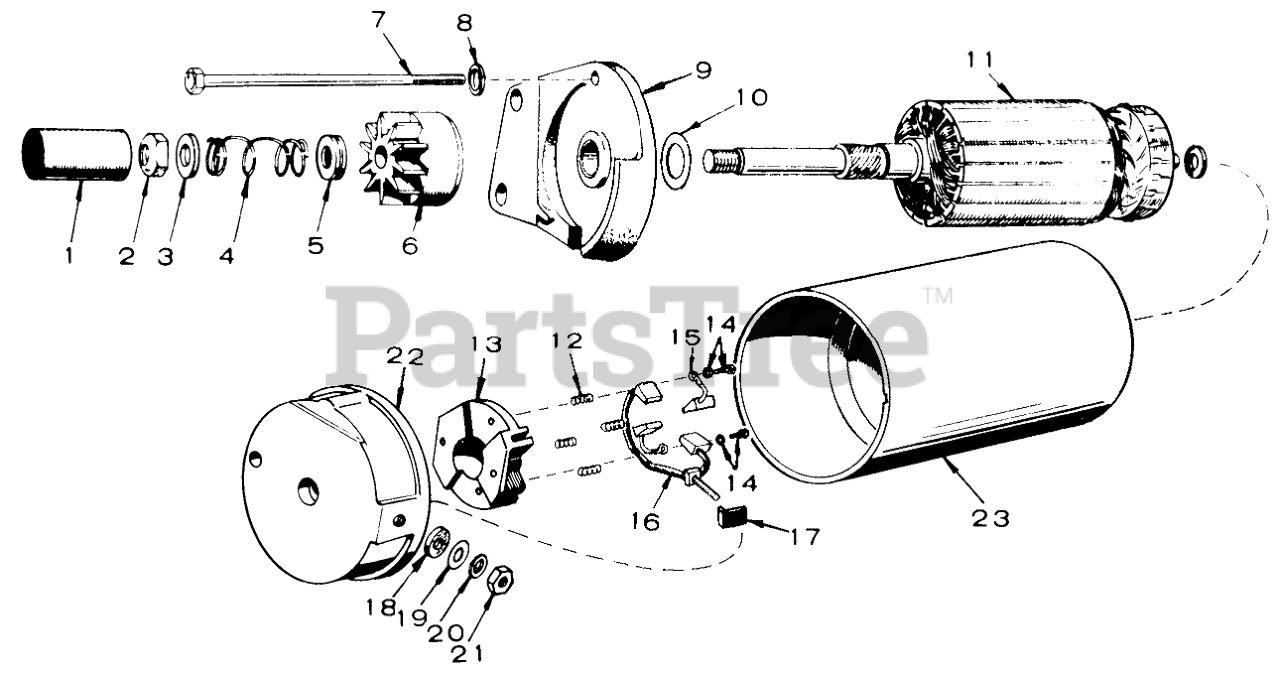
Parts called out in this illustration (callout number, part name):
1	Dust Cover
2	Stop Nut
3	Washer-Stop Nut
4	Spring-Anti Drift
5	Dust Cover Spacer
6	Drive Assembly
7	Tie Bolt
8	Lock Washer
9	Cap Assy-Drive End
10	Armature Thrust Washer
11	Armature
12	Spring, Brush
13	Brush Holder
14	Screw and Lockwosher-Brush and Brush Holder Mounting
15	Brush, Ground
16	Stud and Brush Assembly Input
17	Bushing, Insulotion-Input Stud
18	Washer, Insulation-Input Stud
19	Washer, Flat-Input Stud
20	Washer, Lock-Input Stud
21	Nut, Securing-Input Stud
22	Cap Assembly, Commutator (Includes Parts Marked )
23	Housing, Starter Motor
